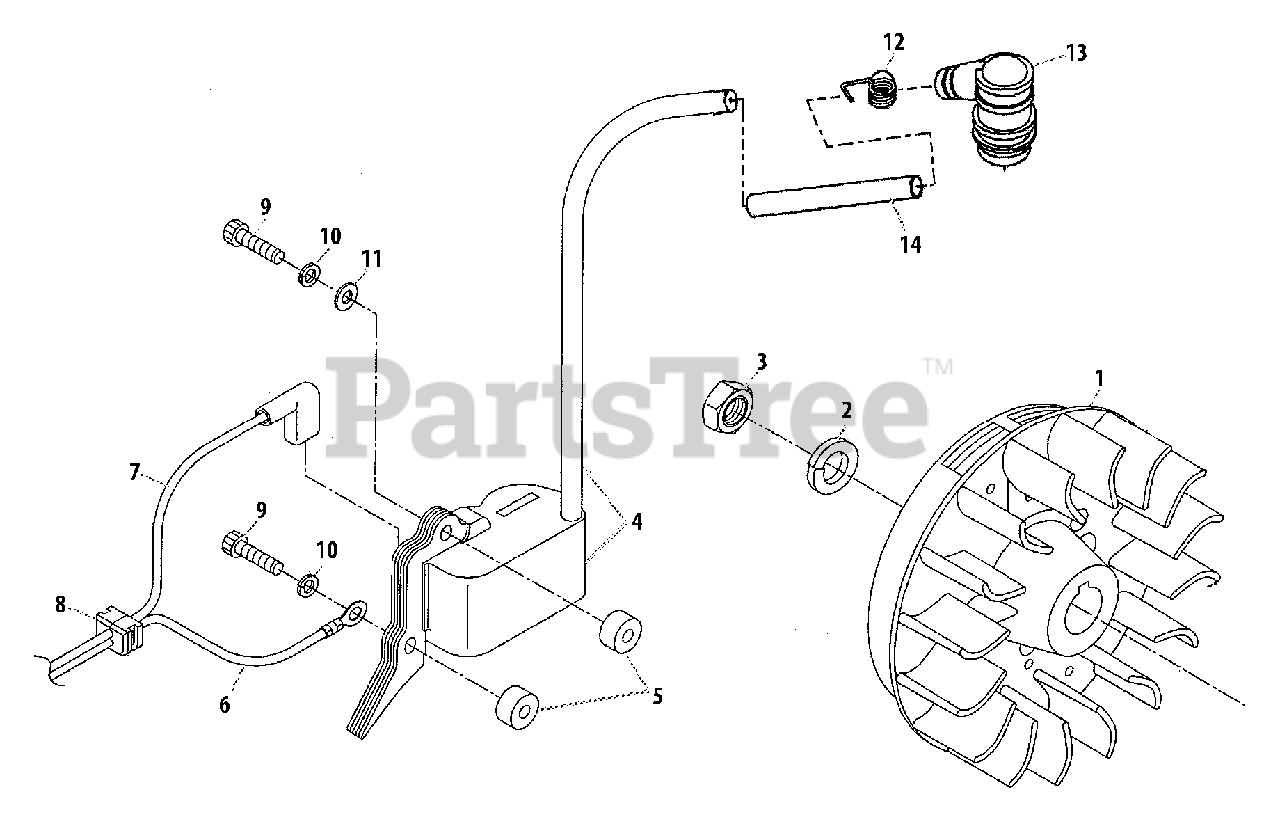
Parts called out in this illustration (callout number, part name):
1	FLYWHEEL
2	LOCKWASHER - 10
3	NUT - 10
4	IGNITION COIL ASSY
5	INSULATOR
6	LEAD - GROUND
7	WIRE
8	GROMMET
9	SCREW - 4X24
10	LOCKWASHER - 4
11	WASHER
12	TERMINAL, SPARK PLUG CAP
13	CAP, SPARK PLUG
14	CORD TUBE - B
